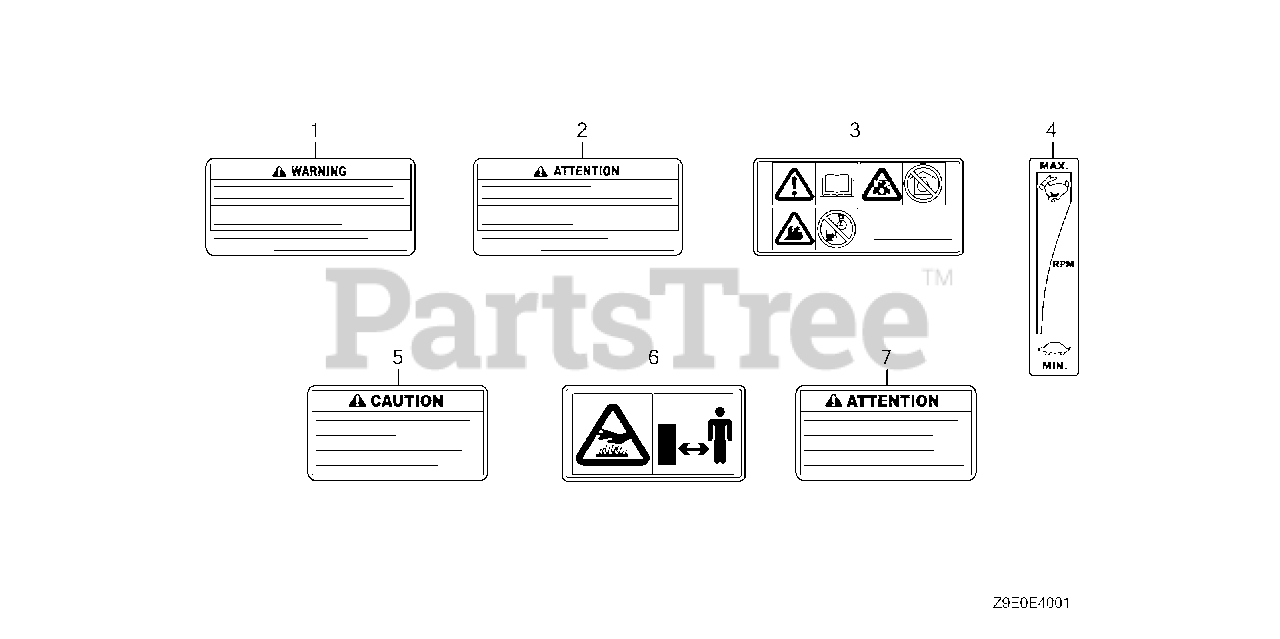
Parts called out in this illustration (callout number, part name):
2	MARK, OPERATOR CAUTION (FRENCH)(MADE IN JAPAN)
3	MARK, OPERATOR CAUTION (PICTOGRAPH)
4	MARK, THROTTLE INDICATION
5	MARK, EX. CAUTION (ENGLISH)
6	MARK, EX. CAUTION (PICTOGRAPH)
7	MARK, EX. CAUTION (FRENCH)
